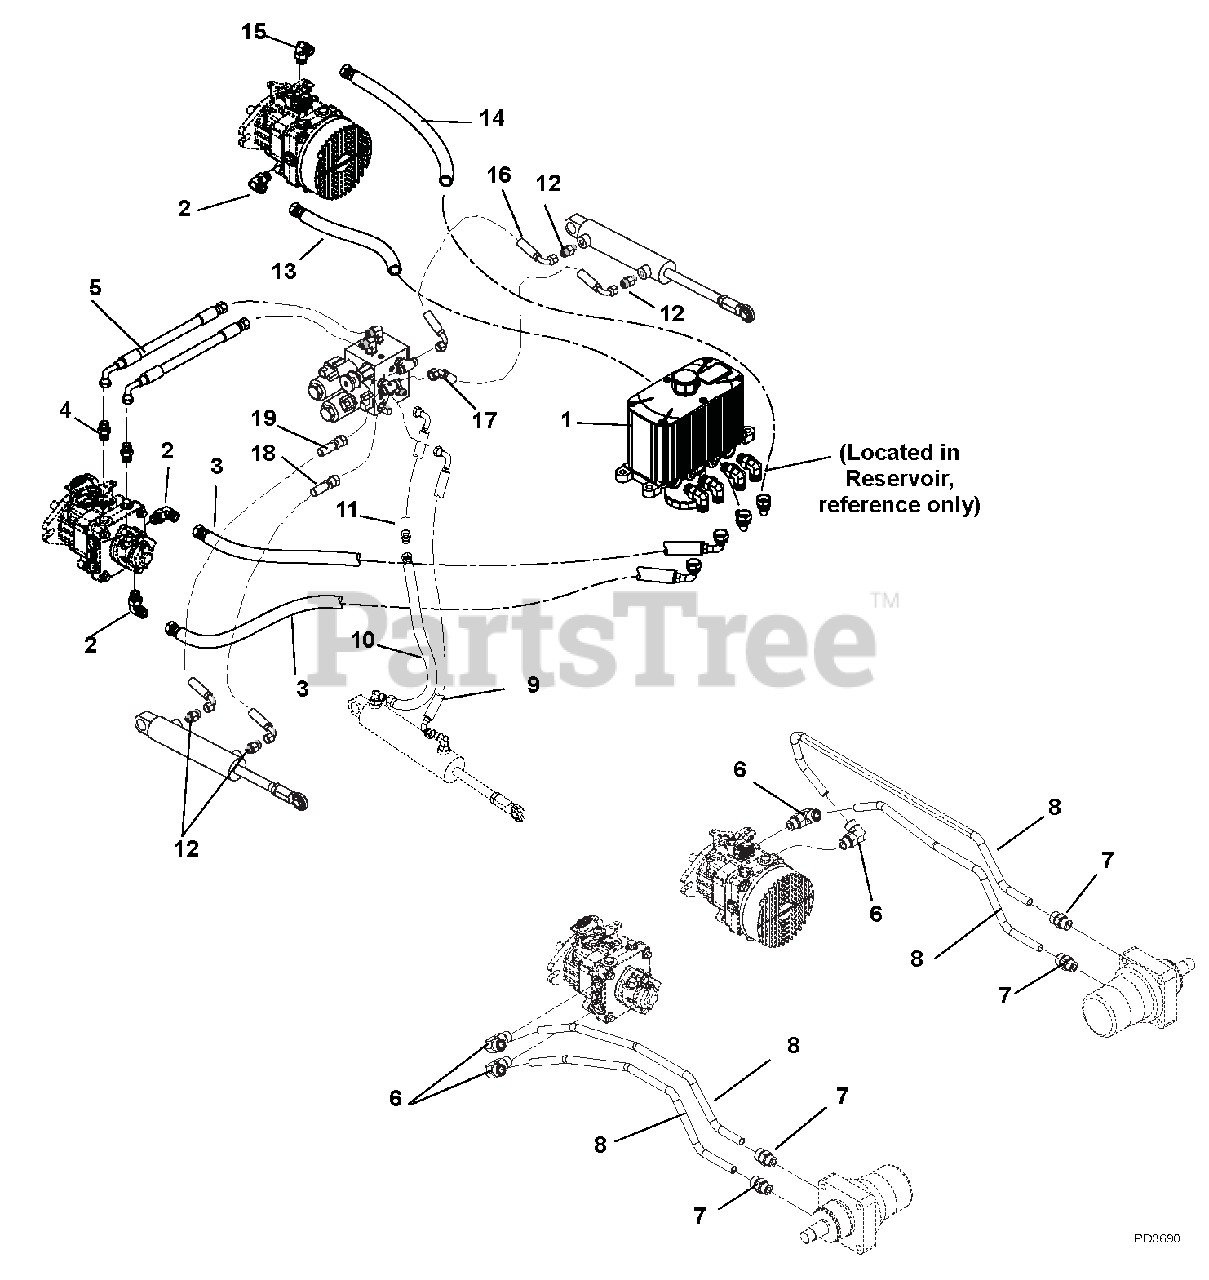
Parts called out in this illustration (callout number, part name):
1	TANK, HYD RESERVOIR/FILTER
2	FTG. HYD. 90 EL M8F-M8O
3	HOSE,HYD .50-15-0K F08F0-F08F9
4	FITTING, HYD STR M40-M6F
5	HOSE,HYD .37-30-2K F06F0-F06F9
6	FTG,HYD 90 M10F-M8O
7	FTG,HYD STR M10O-M10F
8	HOSE,HYD .50-25-2K F10F0-F10F0
9	HOSE,HYD .25-39-2K F04F0-F04F0
10	HOSE,HYD .25-16-2K F04F0-F04F9
11	HOSE,HYD .25-20-2K F04F9-F04F9
12	FITTING, HYD STR M40-M6F
13	HOSE,HYD .5-17.25-0K F8F9-F8F9
14	HOSE,HYD .5-17.25-0K F8F9-F8F9
15	ADPTR,FACE SEAL 8X8 1/2 O-RING
16	HOSE,HYD .38-29-2K F06F9-F06F9
17	HOSE,HYD .38-21-2K F06F9-F06F7
18	HOSE,HYD .38-32-2K F06F9-F06F0
19	HOSE,HYD .38-28-2K F06F9-F06F0
